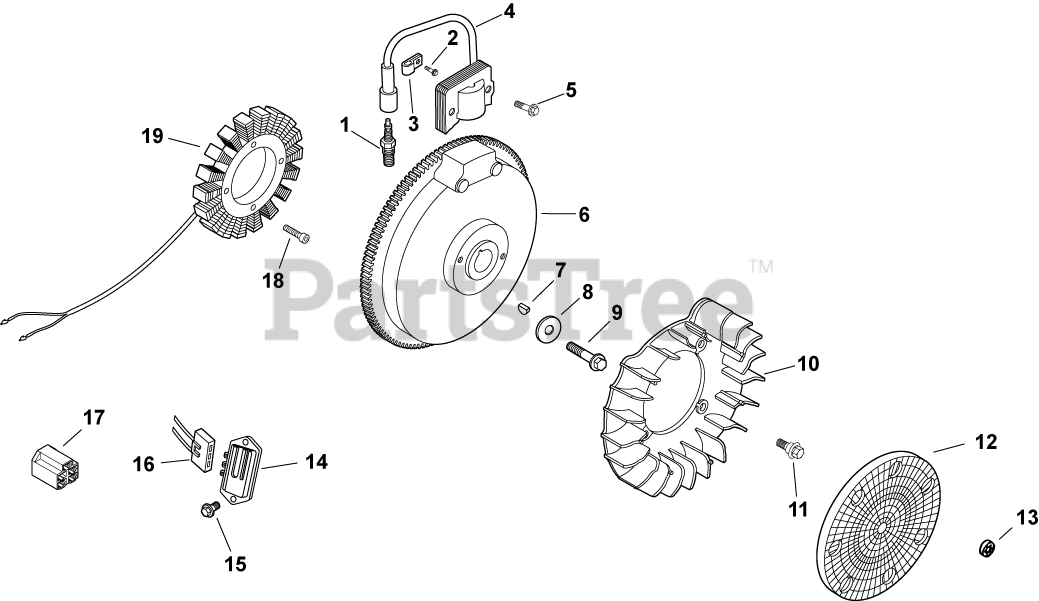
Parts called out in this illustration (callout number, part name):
1	PLUG, SPARK (STD)
2	SCREW, FLG THD FRM M5X.8X10
4	MODULE, IGNITION
5	SCREW, FLG THD FRM M5X.8X20-(#25086399S)
6	FLYWHEEL - USE 12 025 16-S
7	KEY, 3/16" X 5/8"
8	WASHER, FLAT 13/32"
9	SCREW, FLG M10X1.5X45 - (#25086361S)
11	BOLT, SHOULDER
12	SCREEN, GRASS
14	REG/RECT-15 AMP (KM)-USE 41 403 10-S
15	SCREW, FLG M6X1.0X16
16	CONNECTOR, BODY (KM)-USE 25 155 41-S
17	CONNECTOR
18	SCREW, M5X0.8X25 - (#25086402S)
19	KIT, 15 / 20 AMP STATOR
